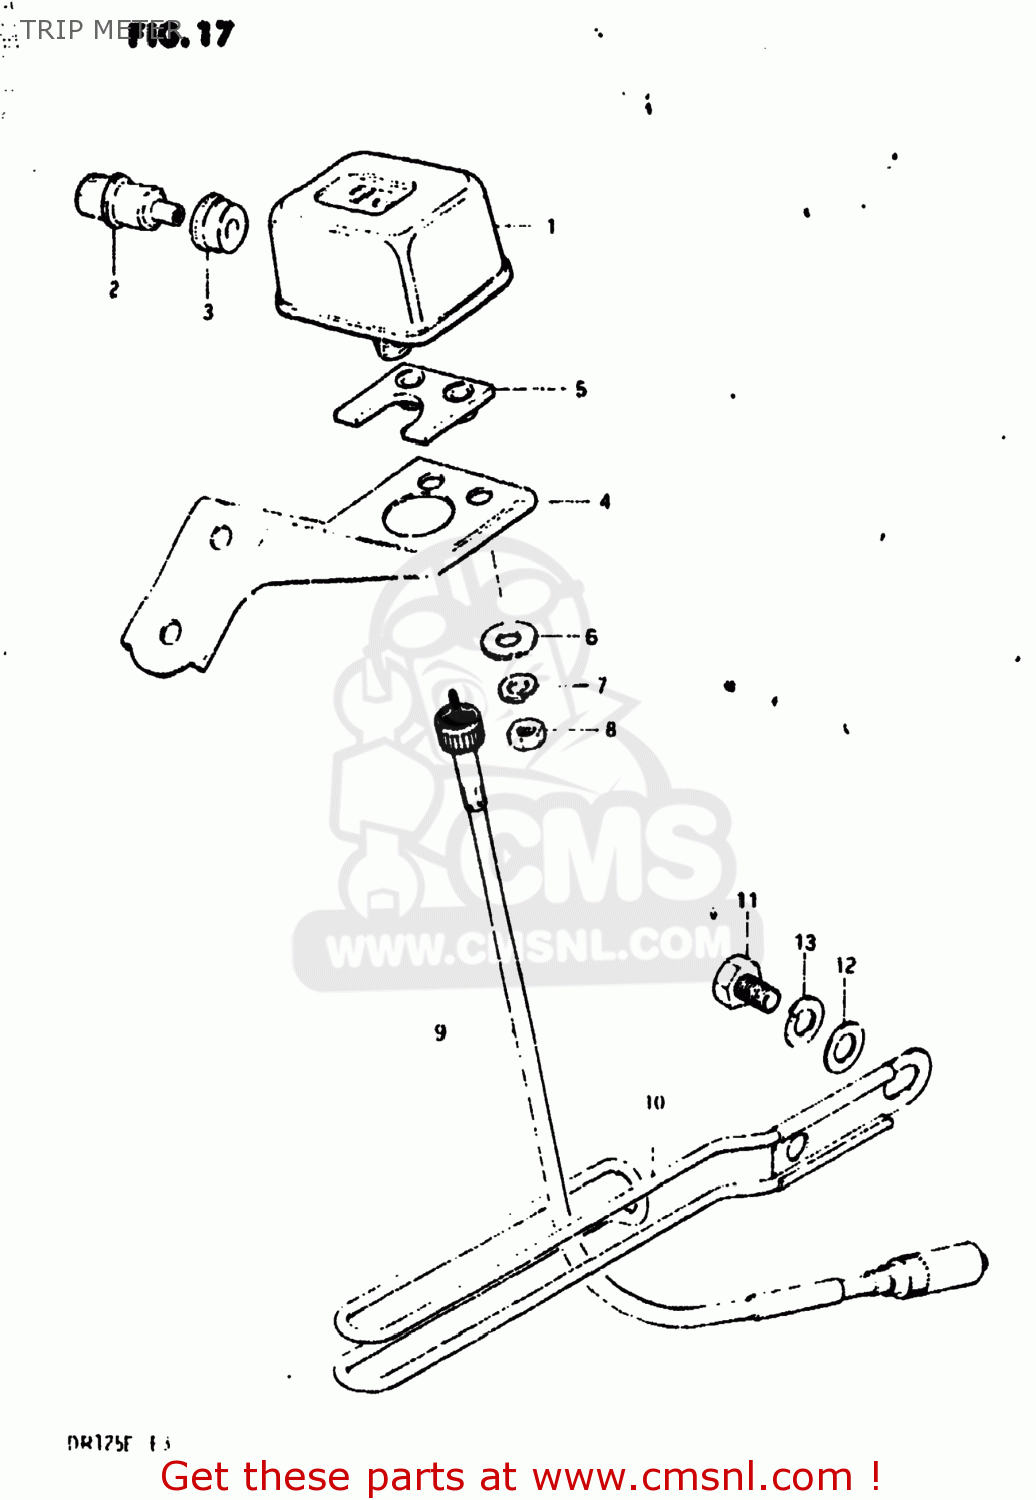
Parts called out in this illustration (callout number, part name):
1	TRIP METER
2	KNOB,TRIP METER
3	COVER,TRIPMETER KNOB
4	BRACKET,TRIPMETER
5	CUSHION,TRIPMETER
6	WASHER,METER
7	LOCK WASHER
8	NUT
9	CABLE ASSEMBLY,SPEEDOMETER
10	GUIDE,CABLE
11	BOLT 8X12
12	WASHER
13	LOCK WASHER
